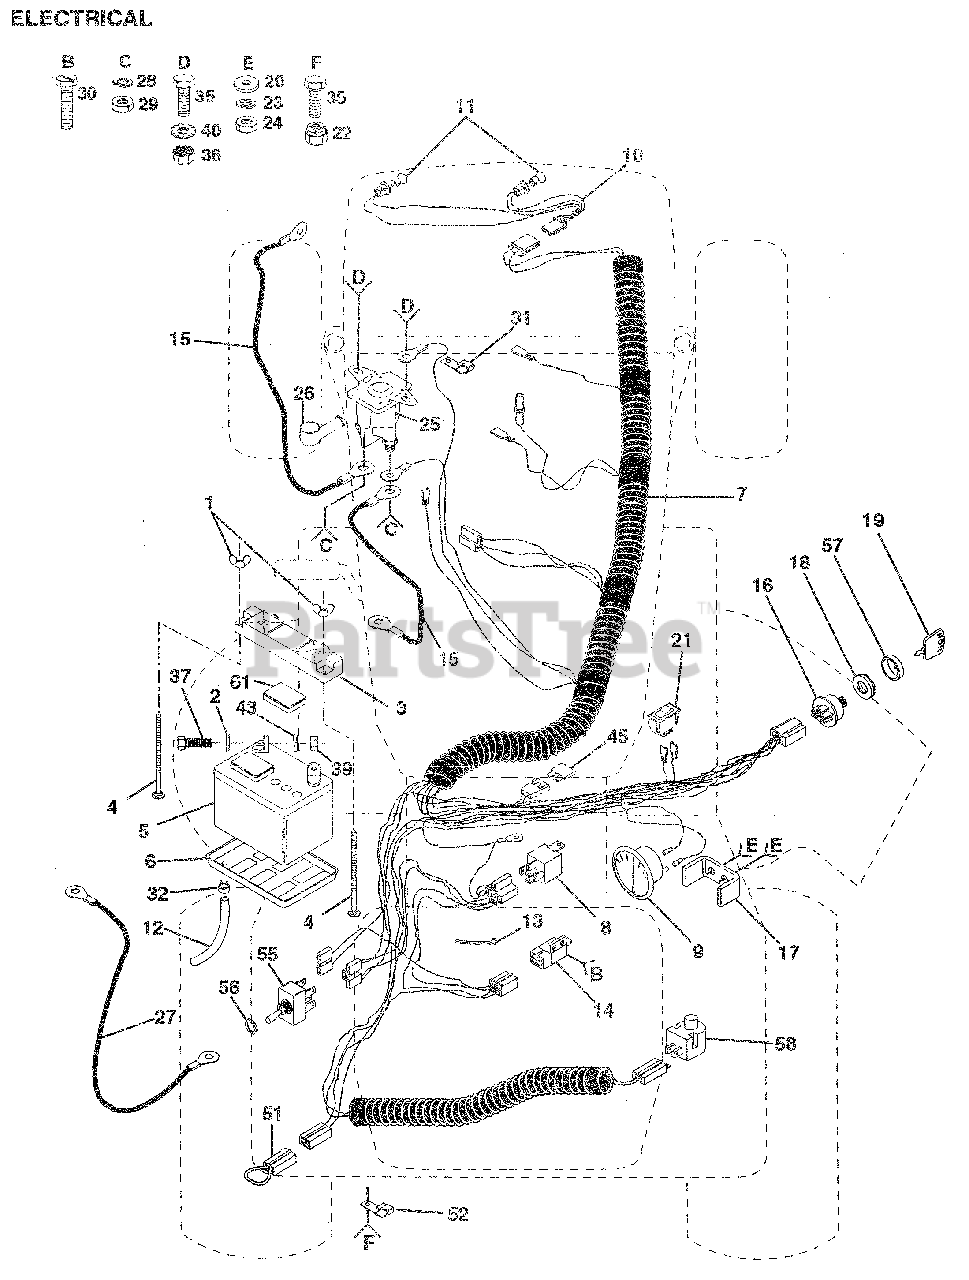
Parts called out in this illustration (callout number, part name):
1	Wing Nut 1/4-20
2	Washer 9/32 x 5/8 x 16 Ga
3	Guard, Terminal
4	Battery Bolt 1/4-20 x 7-1/2
6	Battery Tray
7	Harness, Ignition
8	Relay
9	Ammeter
10	Harness, Light Socket
11	Bulb, Light
12	Tube, Battery Tray
13	Cable Tie
14	Switch, Interlock, Clutch
15	Cable, Battery
16	Ignition Switch
17	Bracket, Ammeter
18	Nut, Ignition
19	Key
20	Washer 7/32 x 1/2 x 18 Gauge
21	Switch, Light
22	Nut, Crownlock 1/4-20
23	Washer, Lock
26	Terminal Cover
27	Cable, Battery
28	Washer, Lock
29	Nut, Hex Jam 1/4 x 20 UNC
30	Screw, Tap, Hex Hd. #10-24 UNC
31	Clip, Fuel Line
32	Clamp, Hose
35	BoIt.Hex 1/4-20 x 1/2 Gr. 5
36	Nut, Keps, Hex 1/4-20
37	Bolt, Hex i/4-20 x 3/4
39	Nut, Hex 1/4-20
40	Washer, Lock 1/4 Ext. Tooth
43	Washer, Lock 1/4
45	Fuse, 30 Amp.
51	Loop, Wire Tiller Attachment
52	Clip, Insulated
55	Switch PTO
56	Nut, Hex
57	Coyer Serv Key
58	Switch, Plunger
61	Caps, Battery Set
